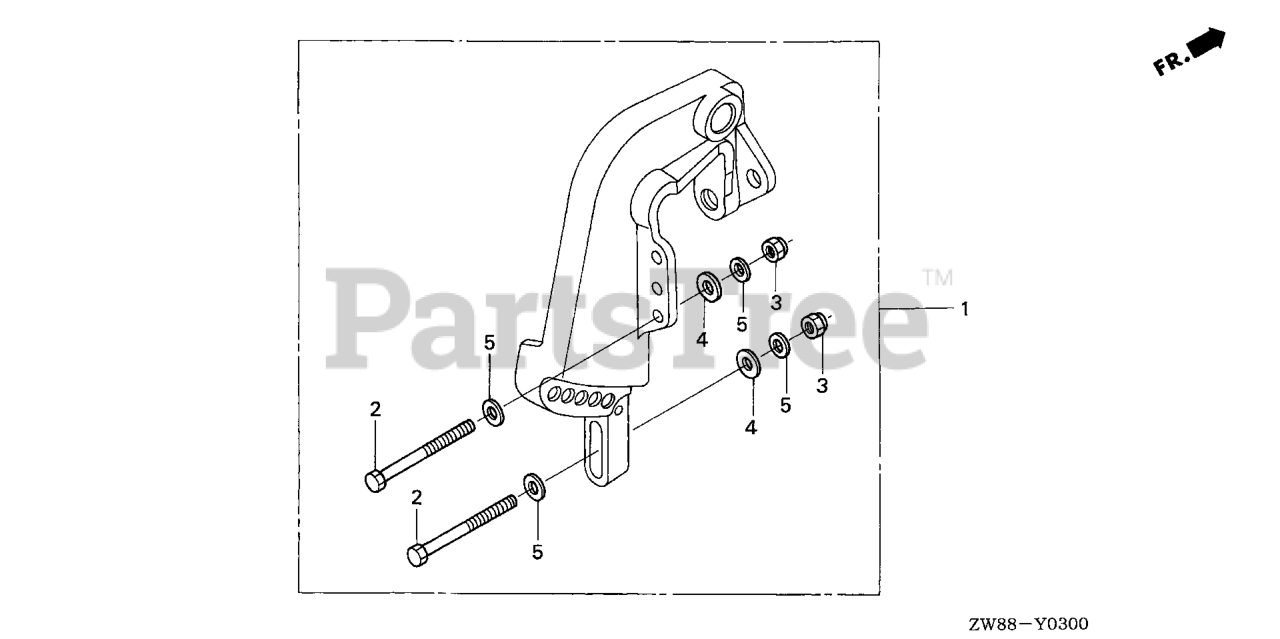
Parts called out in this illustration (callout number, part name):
1	INSTALLATION KIT, OUTBOARD
2	BOLT, HEX. (10X100)
3	NUT, SELF-LOCK (10MM)
4	WASHER, PLAIN (10MM)
5	WASHER, PLAIN (10MM)
